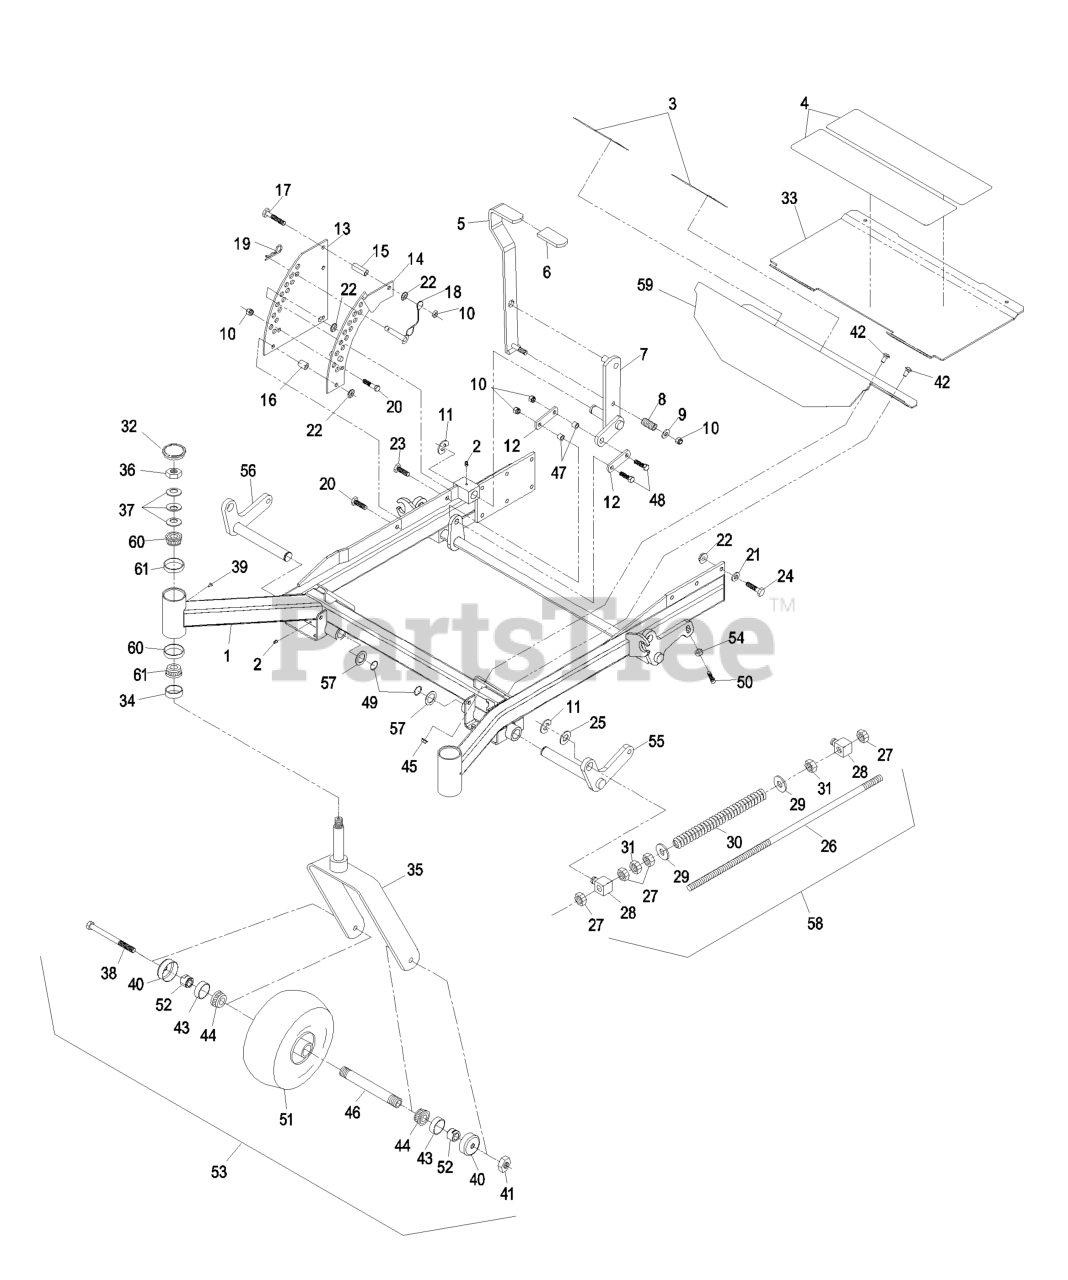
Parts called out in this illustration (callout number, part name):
1	KIT,FRONT FRAME LZ 52
2	FITTING-GREASE
3	PAD-ANTI SKID
4	PAD-ANTISKID
5	LIFT LEVER/GRIP ASM
6	GRIP-LEVER, LIFT
7	ARM-LIFT, DECK
8	SPRING-COMPRESSION
9	WASHER-FLAT
10	NUT-LOCK, NI
11	RING-RETAINING, EXT
12	ARM-LIFT, DECK
13	PLATE-LIFT, DECK
14	Plate Wldmt, Deck Lift
15	BUSHING-LEVER, LIFT
16	BUSHING-LEVER, LIFT
17	SCREW-HH
18	PIN-HITCH (W/LANYARD)
19	PIN-COTTER
20	SCREW-HH
21	WASHER-BELLEVILLE
22	NUT-HHF, WHIZ
23	SCREW-HH
24	SCREW-HH
25	WASHER-FLAT
26	ROD-LIFT, DECK
27	NUT-HEX
28	SWIVEL-DECK MOUNT, REAR
29	WASHER-FLAT
30	SPRING-SUPPORT, DECK
31	NUT-JAM
32	CAP-GREASE
33	ASM,LIFTOUT FLOORPAN/PAD
34	SEAL-GREASE
36	NUT-LOCK, NI
37	WASHER-BELLVILLE
38	SCREW-HH
40	GUARD-SEAL
41	NUT-LOCK, NI
42	BOLT-CARR
43	SEAL-CASTER
44	BEARING-CONE, TAPERED ROLLER
47	BUSHING
48	SCREW-HH
49	RING-RETAINING
50	SCREW-HSH
52	SPACER-NUT
53	ASM, WHEEL AND TIRE W/ AX
54	NUT-JAM
55	WLD, FRONT LIFT SHAFT - L
56	WLD,FRONT LIFT SHAFT RH
57	WASHER-SPACER
58	FRONT FRAME SPRING ASM
60	Cone-Bearing Tapered Roller
61	CUP-BEARING
